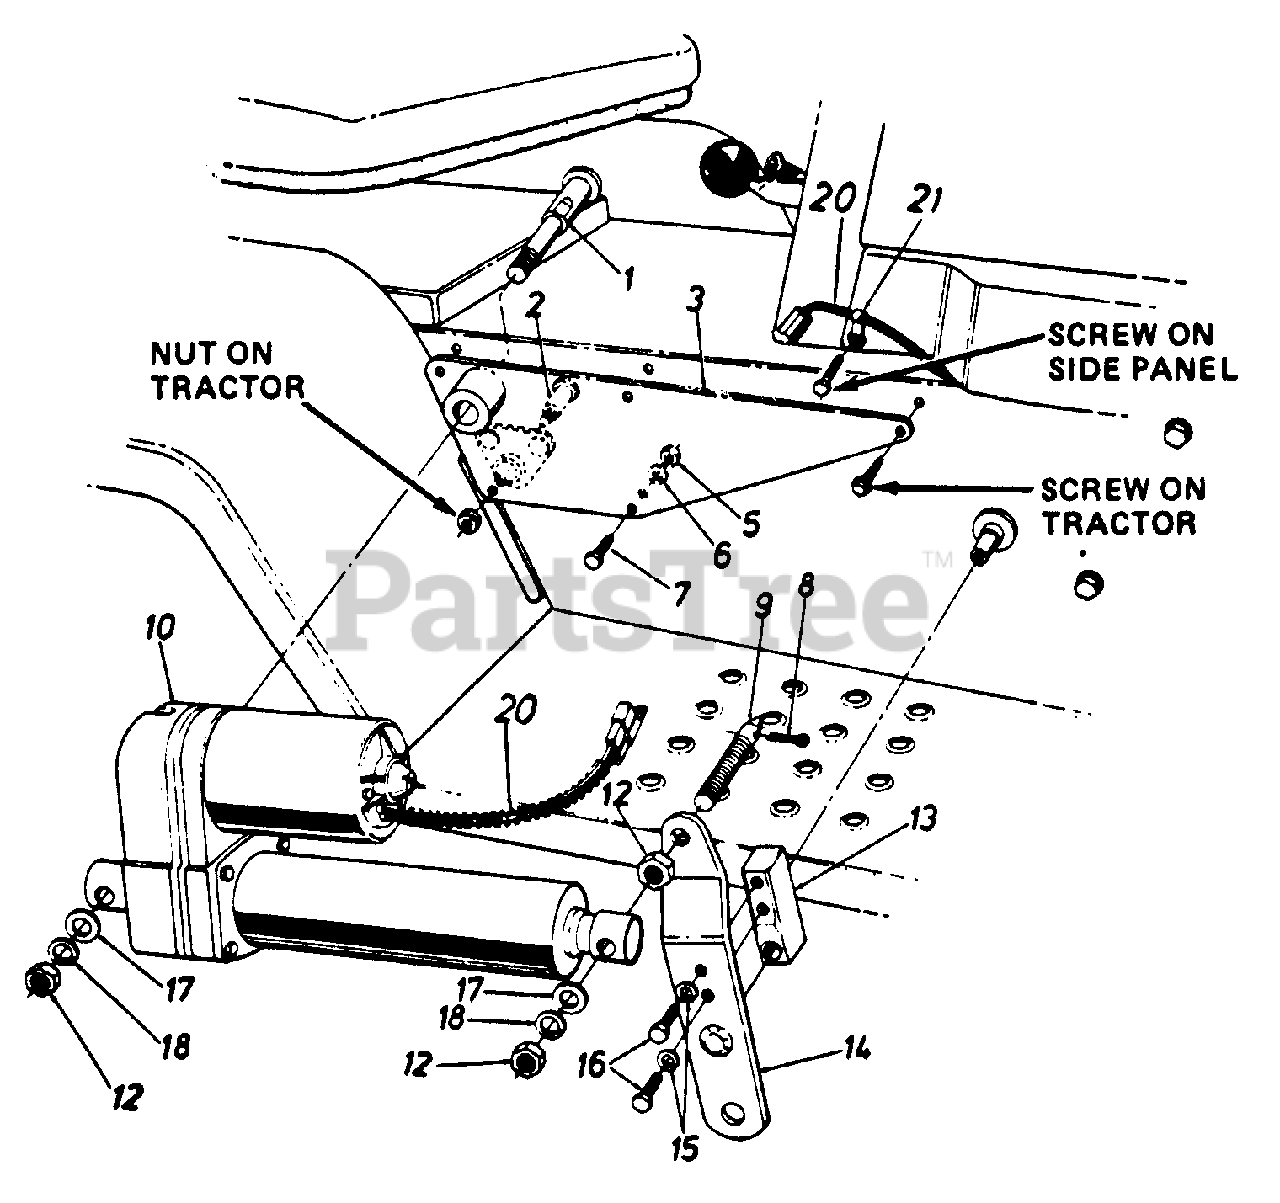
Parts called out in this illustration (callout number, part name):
2	Shld. Bolt .626 Dia. x .96"
5	Hex Nut 1/4-28 Thd.
6	L-Wash. 1/4" I.D.
7	Hex Bolt 1/4-28 x .75" Lg. (Grade 5)
9	Indicator & Mtg. Pin
10	Electric Actuator
12	Hex Jam Nut 1/2-13 Thd.
13	Lift Shaft Drive
16	Hex Bolt 5/16-24 x 1.0" Lg. (Grade 5)
17	Fl-Wash. .53" I.D. x.93" O.D
18	L-Wash. 1/2" I.D.
20	Plastic Tubing-7"
